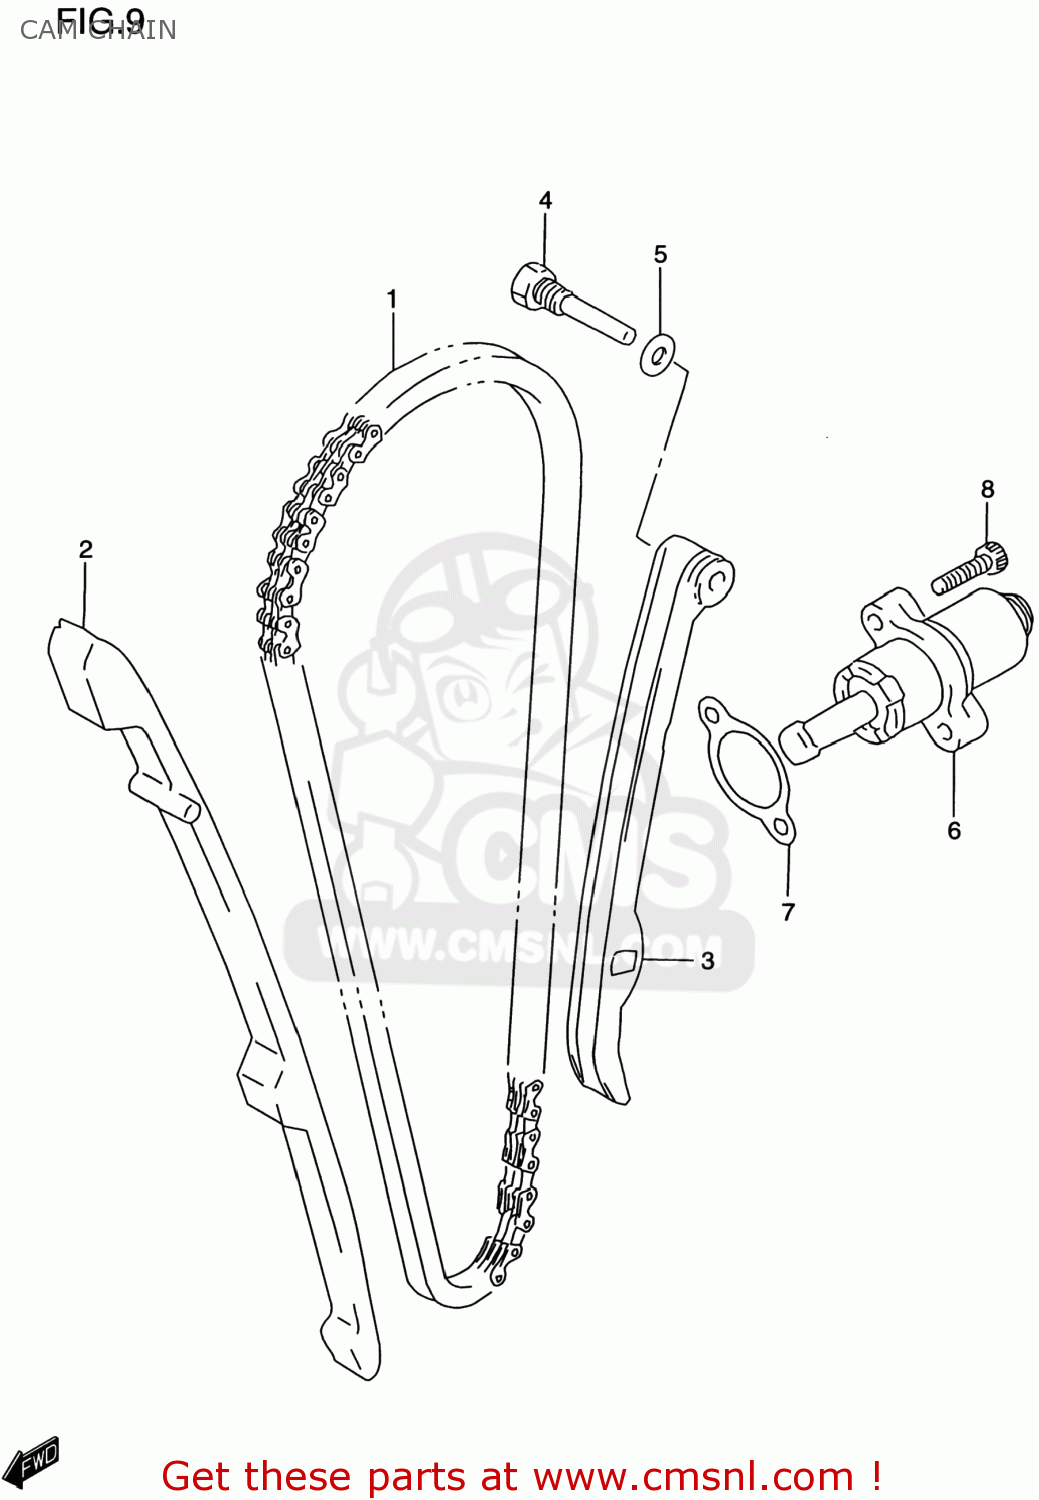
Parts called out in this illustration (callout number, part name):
1	CHAIN,CAMSHAFT DRIVE
2	GUIDE,CAM CHAIN
3	TENSIONER,CAM CHAIN
4	BOLT,CAM CHAIN TENSIONER
5	GASKET 8.2X14X1 (NAS)
6	ADJUSTER ASSY,TENSIONER
7	GASKET,TENSIONER ADJUSTER (NAS)
8	BOLT,CL.COVER
